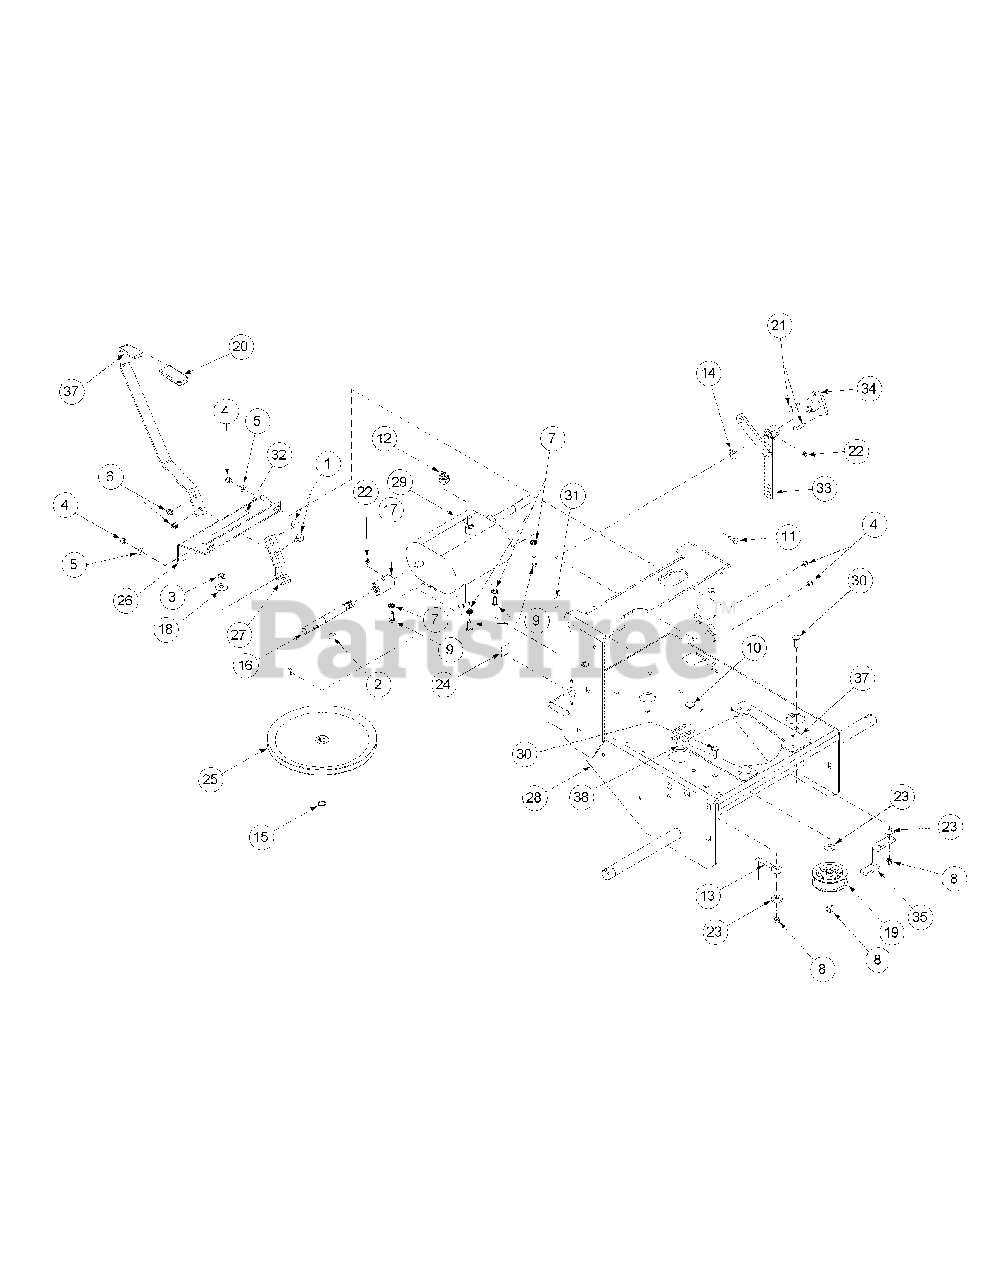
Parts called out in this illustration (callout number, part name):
1	Carriage Bolt, 5/16-18 x 1
2	Woodruff Key, 3/16 x 3/4
3	Jam Nut, Insert Lock, 3/8-24
4	Lock Nut, Nylon Insert, 1/4-20
5	Flat Washer, 1/4 Zinc
6	Nut, 5/16-18 Nylock
7	Lock Washer, 5/16 Zinc
8	Lock Nut, Nylon Insert, 3/8-16
9	Hex Cap Screw, 5/16-18 x 3/4
10	Carriage Bolt, 3/8-16 x2
11	Carriage Bolt, 1/4-20 x .750
12	Switch, WB Transmission
13	Drive Belt Guide
14	E-Ring, 5/8
15	External Retainer Ring
16	Jackshaft w/ Heavy Spline
17	Coupling w/Heavy Spline
18	Bell Washer, .39 ID x 1.13 OD x .062
19	Flat Idler Pulley w/Adapter
20	Grip, .250 x 1 x 3-1/2, Yellow
21	Carriage Bolt, 1/4-20 x 1.00
22	Grease Fitting, 1/4-28 x 3/16
23	Idler Washer
24	Decal "Made In America
25	Transmission Pulley
27	Shift Arm
28	Engine Deck Assembly
29	Transmission, 5 Speed
30	Carriage Bolt, 3/8 -16 x 1.25
31	Label, Warning, Open Belt Drive
32	Label, Mower Instruction
33	Clutch, Bellecrank Casting
34	Bellecrank Pivot, Weldment
35	Engine Belt Guide
37	Engine Spacer, LH
38	Engine Spacer, RH
